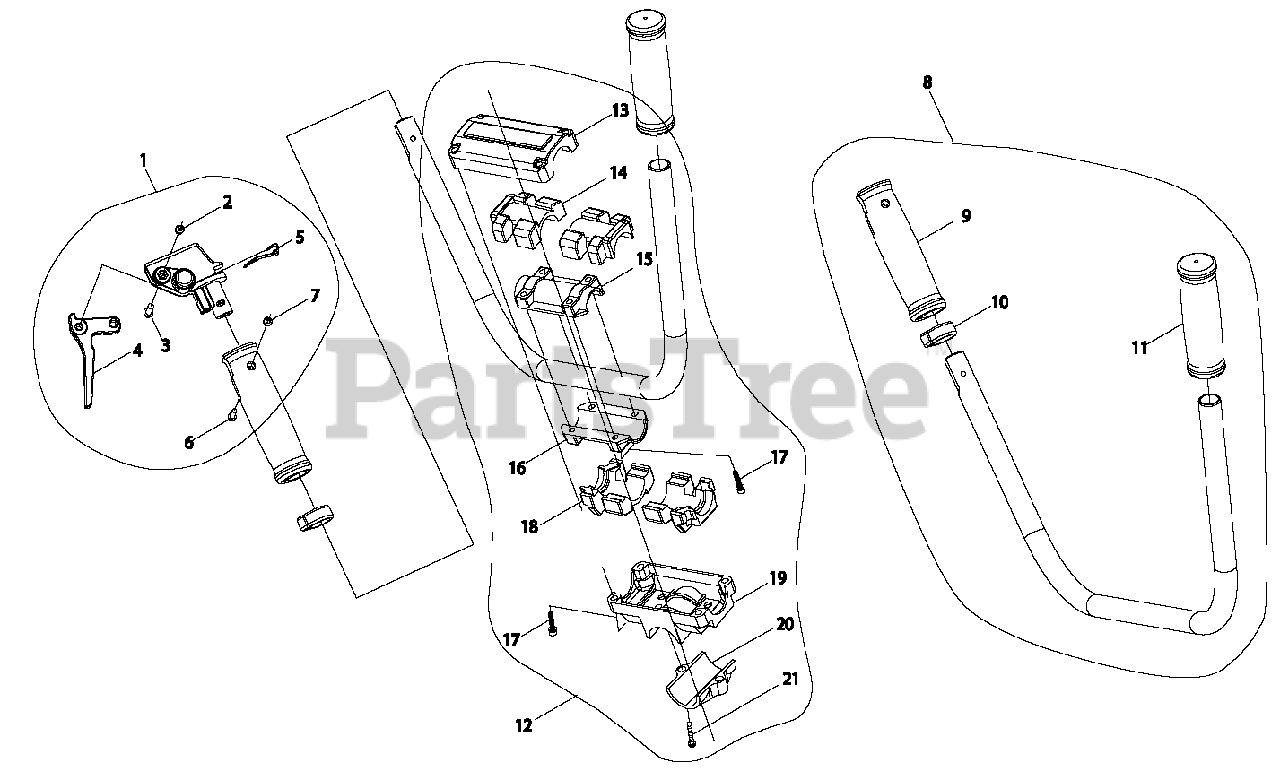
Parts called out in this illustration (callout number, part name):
1	THROTTLE CONTROL ASSY
2	LOCKNUT - 5
3	BOLT
4	TRIGGER, THROTTLE
5	STOP, THROTTLE
6	BOLT - 4X24
7	NUT - 4 -- NYLON
8	HANDLE ASSY
9	GRIP - RIGHT
10	HOLDER, CABLE
11	GRIP - LEFT
12	HANDLE BRACKET KIT
13	BRACKET, HANDLE - UPPER
14	CUSHION - UPPER
15	CLAMP - UPPER
16	CLAMP - LOWER
17	SCREW - 5X25
18	CUSHION - LOWER
19	BRACKET, HANDLE - LOWER
20	BRACKET, MOUNTING
21	SCREW - 6X25
